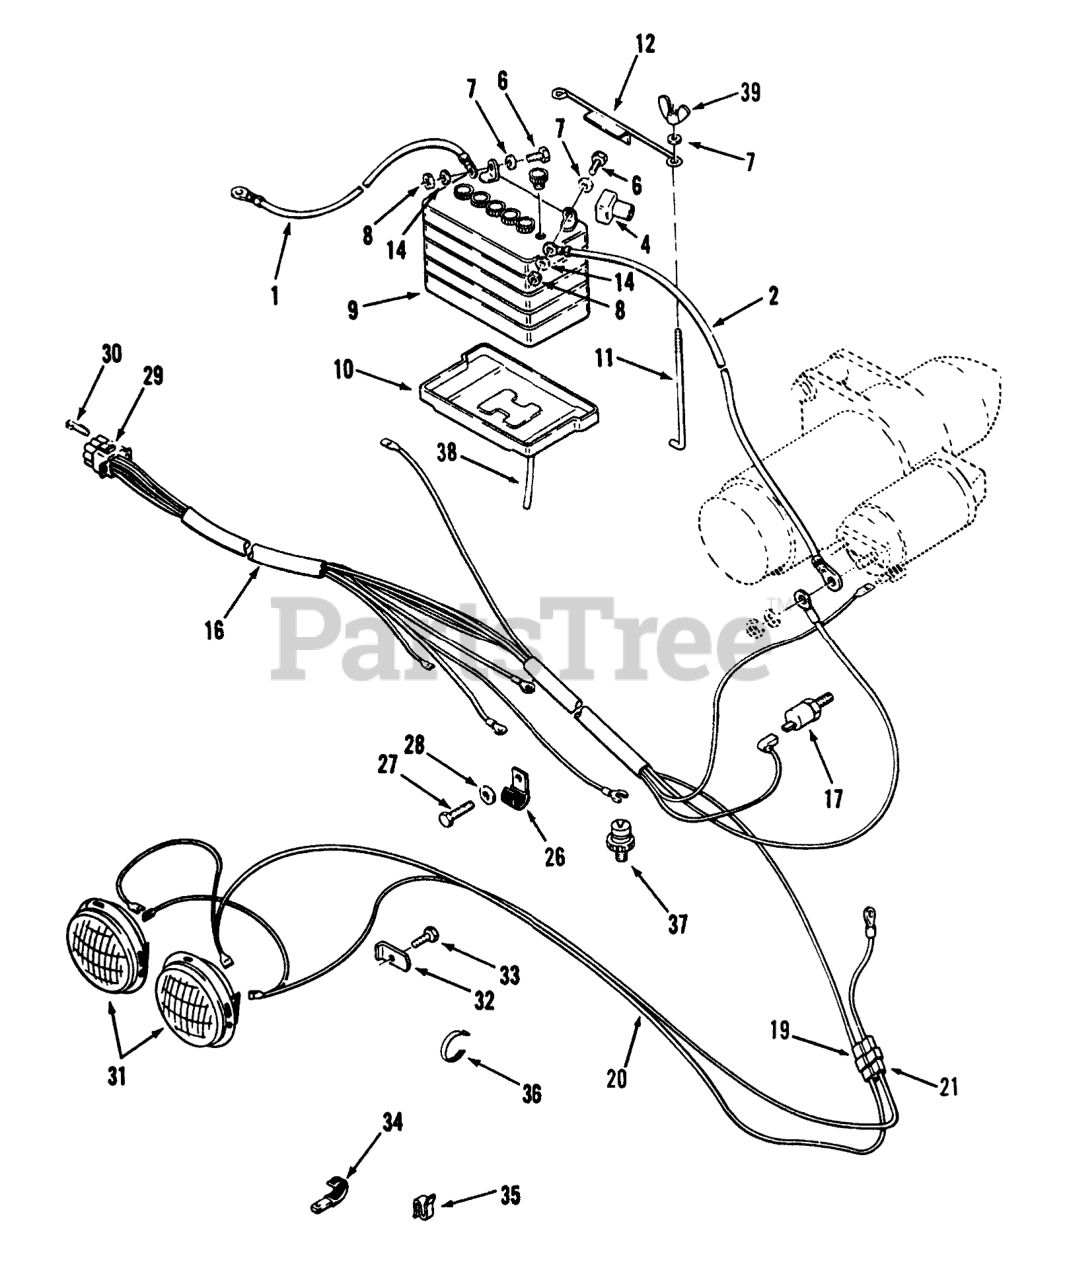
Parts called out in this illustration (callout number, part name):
1	ASS'Y-WIRE
2	ASS'Y-WIRE
4	Boot
6	SCREW-HH
7	WASHER-FLAT
8	NUT-LOCK, NI
9	Battery
10	TRAY-BATTERY
11	HOOK-BATTERY RETAIN
12	HOLDDOWN-BATTERY
14	WASHER-LOCK
16	WIRING HARNESS
17	HIGH TEMPERATURE
19	MALE CONNECTOR
20	HARNESS-HEADLIGHT
21	CONNECTOR BODY
26	CLIP-WIRE
27	SCREW-HWH
28	LOCKWASHER 1/4 IT
29	CONNECTOR CAP
30	CONTACT SOCKET
31	HEADLAMP
32	LOCK-HEADLIGHT
33	Bolt
34	CLIP
35	SPEED CLIP
36	PLASTIC TIE
37	SWITCH
38	TUBE-21" BATTERY DRAIN
39	NUT-WING
